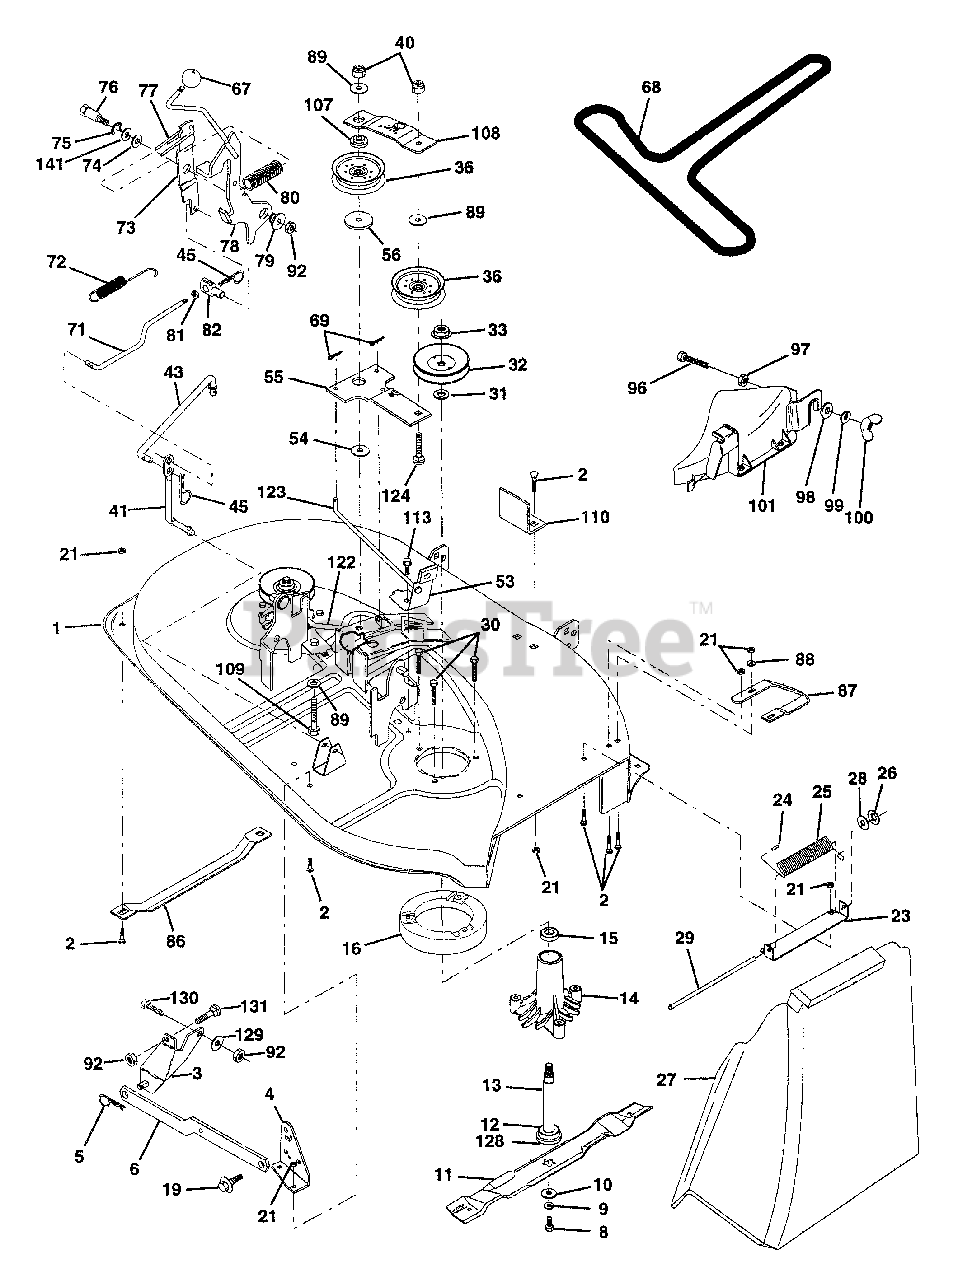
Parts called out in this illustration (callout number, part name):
1	Deck Asm Weldment
2	Bolt Rdhd Sqnk 5/16-18unc X3/4
3	Bracket Asm Fr Sway Bar 38/42
4	Bracket Asm Deck Sway Bar
5	Retainer Spring
6	Arm Suspension Rear
8	Bolt 3/8 - 24 X 1.25 Gr 8
9	Washer Lock Hvy 3/8
10	Washer Hard Blade Mower Vented
11	Blade Mower Mulching 38"
12	Bearing Ball #6024 (Mandrel)
13	Shaft Asm W/lower Bearing
14	Housing Mandrel Vented
15	Bearing Ball Mandrel
16	Stripper Mower Vented
19	Bolt Shoulder
21	Nut Crownlock 5/16-18 UNC
23	Bracket Deflector Mower
24	Cap Sleeve 80x 112 Blk Mower
25	Spring Torsion Deflector 2 52
26	Nut Push Phos & Oil
27	Shield Deflector
28	Washer 11/32 X 5/8 X 16 Ga
30	Screw Thd Rolling Washer Head
31	Washer Spacer Mower Vented
32	Pulley Mandrel
33	Nut 9/16 Toplock Flng Oil Dip
36	Pulley Idler Flat 3 060
40	Nut Crownlock 3/8-16 UNC
41	Rod Pivot W/nibs
43	Rod Clutch Secondary
45	Spring Retainer 1" Zinc/cad
54	Washer Hardened
56	Spacer Retainer Pm Mower
67	Knob Rd 7/16-14 Plastic Thds Blk
68	V-Belt Mower
69	Pin, Cotter 3/32 x 3/4
71	Rod Clutch Primary 38/42
72	Spring Return
73	Arm Clutch Secondary
74	Washer 25/32 X 1-5/8 X 16 Ga
75	Ring Klip #t5304-75
76	Bolt Shoulder 3/8-16 Unc 1 44
77	Keeper Spring 4 000
78	Arm Asm Clutch Primary
79	Bushing 747 Od X 794 Lg Brass
80	Spring Clutch Mower
81	Nut Hex Jam 3/8-16
82	Trunnion Adj 94
86	Runner, LH
87	Runner, RH
88	Washer 11/32 x 3/4 x 16 Ga.
89	Washer 13/32 x 1 x 12 Ga.
92	Nut Lock Hex W/Ins 3/8-16 Unc
96	Bolt 3/8-16 x 1-1/4 Mulcher
97	Nut Crownlock 3/8-16 UNC
98	Washer 13/32 x 1-1/4 x 16 Ga.
99	Washer Lock Hvy Hlcl Spr 3/8
101	Cover Asm Mulching 38"
107	Spacer, Retainer
108	Stiffener, Idler Arm
109	Bolt, Hex Head 3/8-16 x 2-1/2
110	Upstop Deck Front 38"
113	Screw Thdrol 5/16-18 X 3/4
122	Rod, Brake, LH
123	Rod, Brake, RH
124	Bolt, Carriage 3/8-16 x 1-3/4
128	Washer Felt
129	Washer 13/32 x 13/16 x 12 Ga.
130	Bolt, Fin Hex 3/8-16 UNC x 1 Gr. 5
131	Bolt, Rdhd Sqnk 3/8-16 x 1
141	Washer Thrust .75 x 1.230
